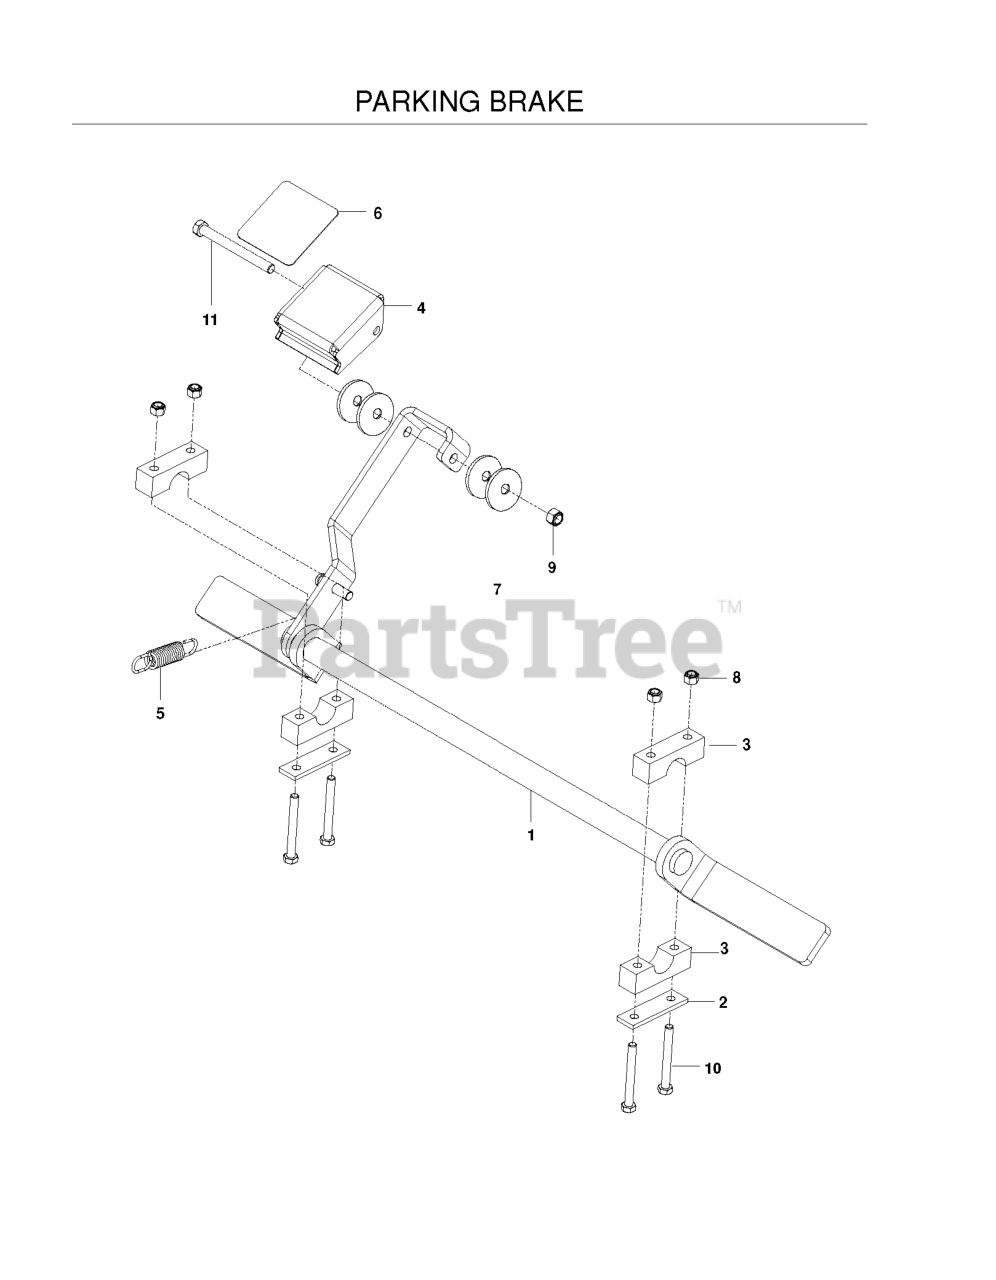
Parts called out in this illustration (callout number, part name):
1	PARK BRAKE
2	REINFORCEMENT BAR
3	PILLOW BLOCK
4	PEDAL, BLACK
5	SPRING, EXTENSION
6	ANTI-SKID PAD
7	WASHER, FRICTION
8	NUT 5/16 NYLOC
9	NUT 3/8-16 NYLOC
10	HCS 5/16C X 2-3/4
11	HCS3/8-16.X
